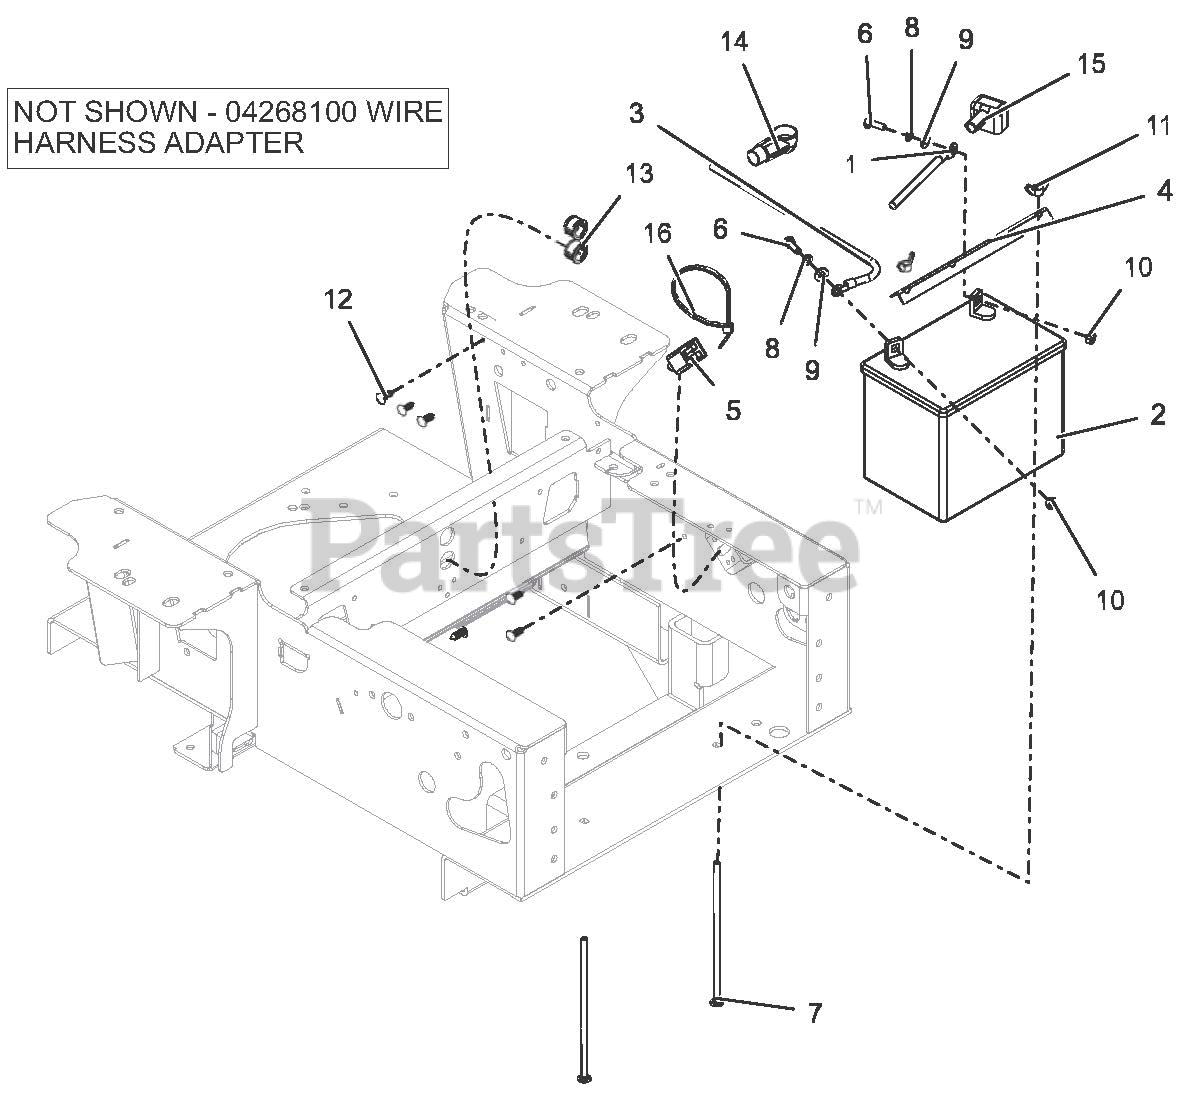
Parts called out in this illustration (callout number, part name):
1	CABLE, POS W/(2) 5/16 RING 30.0 LG
2	BATTERY, 300 CCA 10U1L
3	CABLE, NEGATIVE BATTERY 24"
4	HOLD DOWN - BLK
5	SWITCH, SNAP IN -N.O./N.O
6	BLT-HEX .25-20X.75 GR5 YWZC
7	BLT-RDHDSQNK .25-20X7.50 G2 YWZC
8	WSHR-LK .25X.062 REG YWZC
9	WSHR-FL-STL.281X.62X.065 YWZC
10	NUT-HEX .25-20 YWZC
11	NUT-LOCKING WING 1/4-20
12	RIVET, .25 NYLON PANEL
13	BUSH, PANEL SNAP .687X.875X.56
14	BOOT, .65 ID POS
15	INSULATOR
16	CABLE, TIE 5.50 LG
